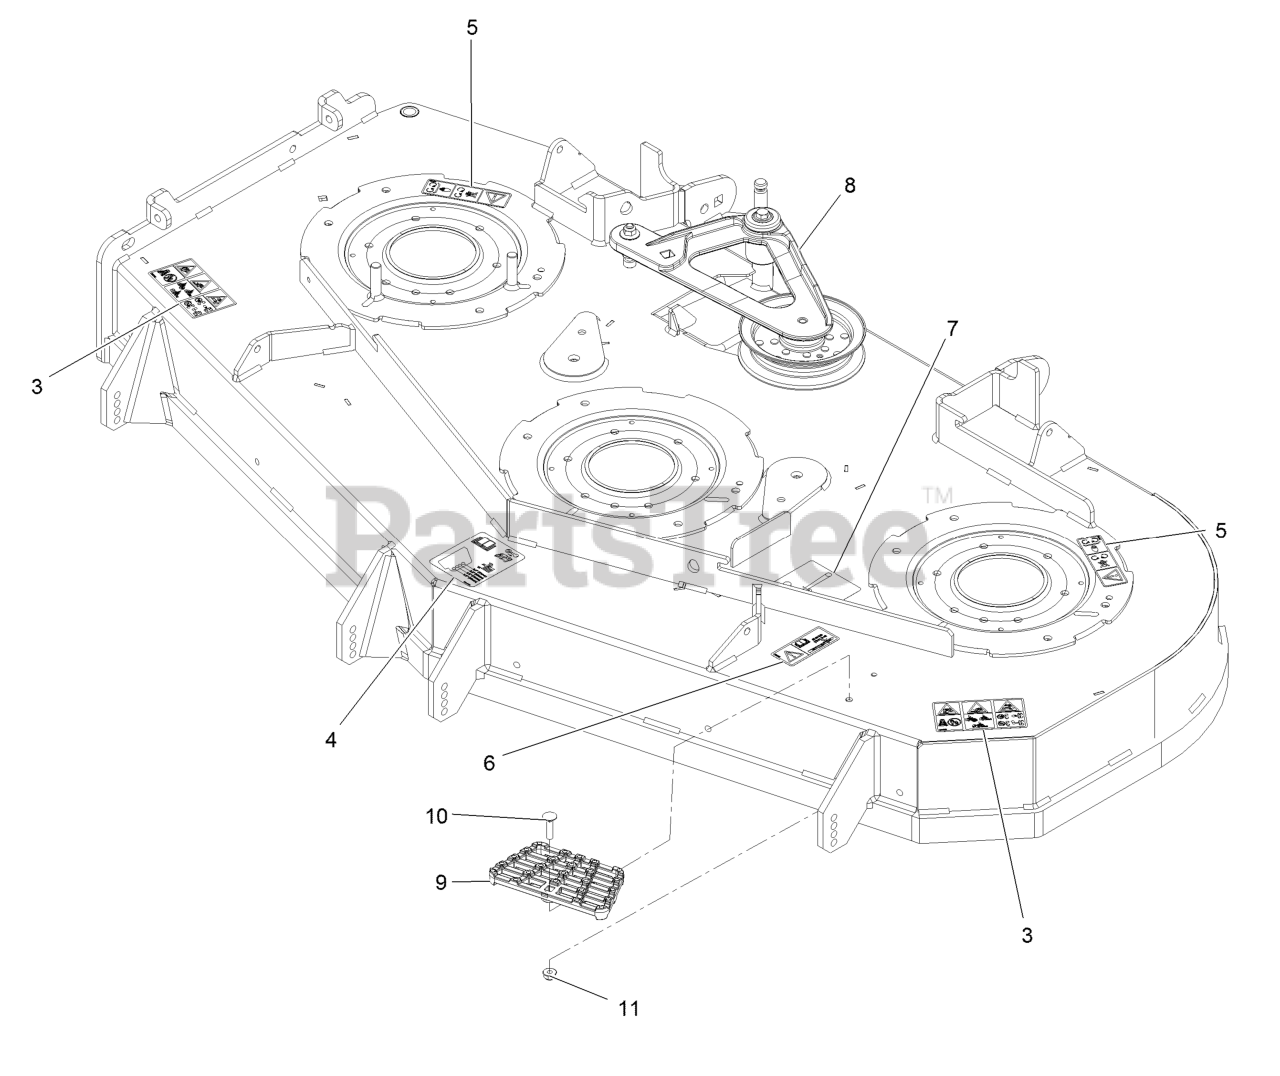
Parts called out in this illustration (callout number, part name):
3	Decal-Danger Thrown Objects
4	Decal-Roller, Anti-Scalp
5	Decal-Missing, Cover
6	Decal-Bolt Torque
7	Decal-Belt Routing
8	Deck Idler ASM
9	Step-Deck
10	Bolt-Carriage 5/16-18 X 1 1/4
11	Nut-Nyloc 5/16-18 Flg
